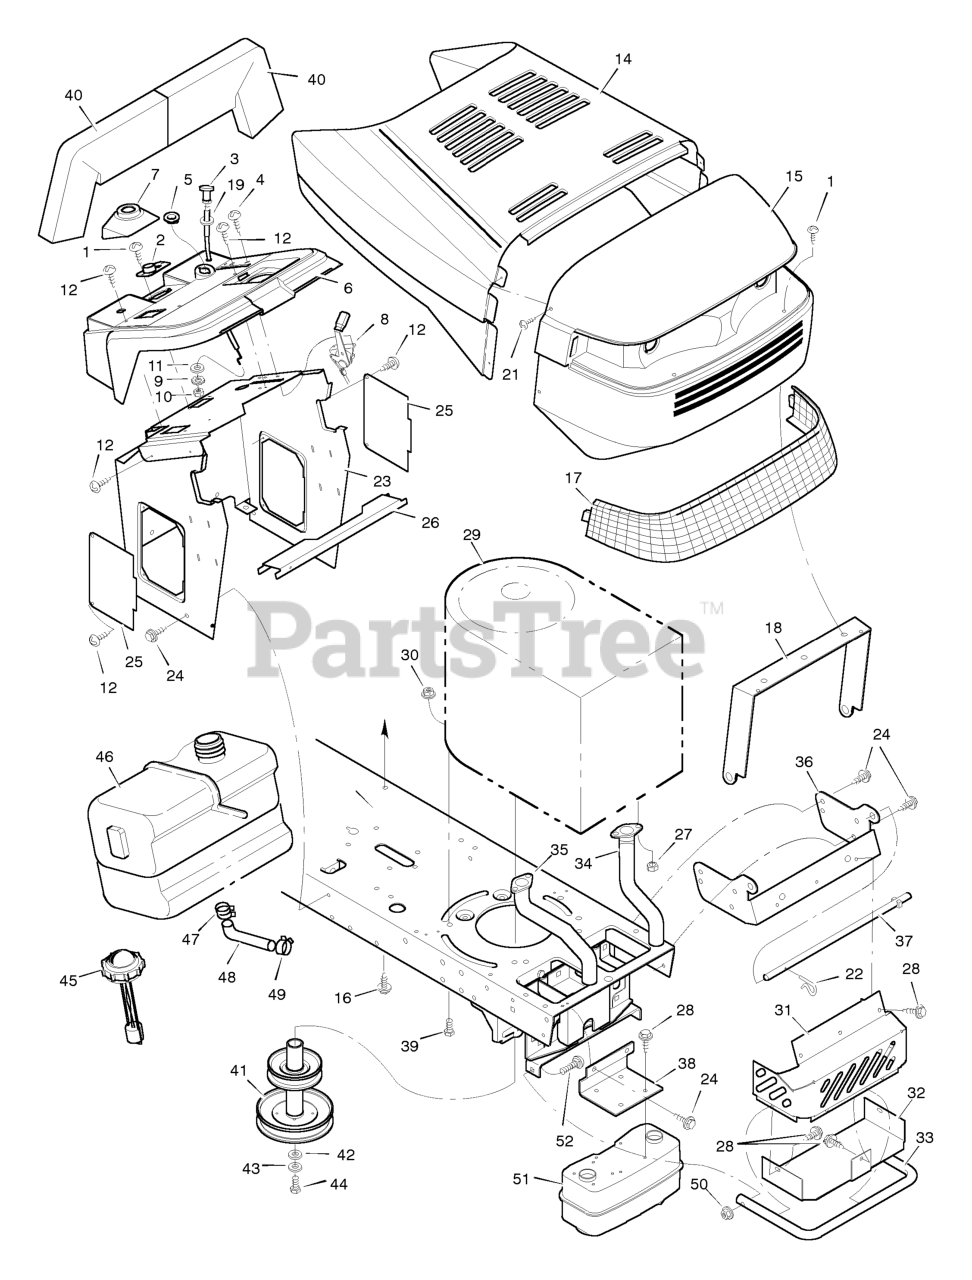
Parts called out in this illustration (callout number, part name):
2	Bearing, Steering Post
3	Cable, Choke
5	Bushing
7	Support, Bellows
8	Throttle Control
9	Lockwasher
10	Nut, Hex
11	Washer
12	Screw
15	Grille
18	Brace, Grille
19	Washer
22	Pin, Hair
23	Console Assembly
25	Panel, Side Access
26	Support, Fuel Tank
27	Nut, Hex
29	Engine *
30	Nut, Flange
31	Shield, Heat
32	Shield, Lower Heat
33	Guard, Muffler
34	Pipe, Left Exhaust
35	Pipe, Right Exhaust
36	Support, Grille
37	Rod, Pivot
38	Bracket, Muffler
39	Bolt, Hex
40	Baffle, Foam
41	Pulley Assembly, Stack
43	Lockwasher
44	Bolt, Hex
45	Cap, Fuel
46	Fuel Tank
47	Clamp, Hose
48	Fuel Line
49	Clamp, Hose
50	Hex, Flange nut
51	Muffler
52	Carriage Bolt
